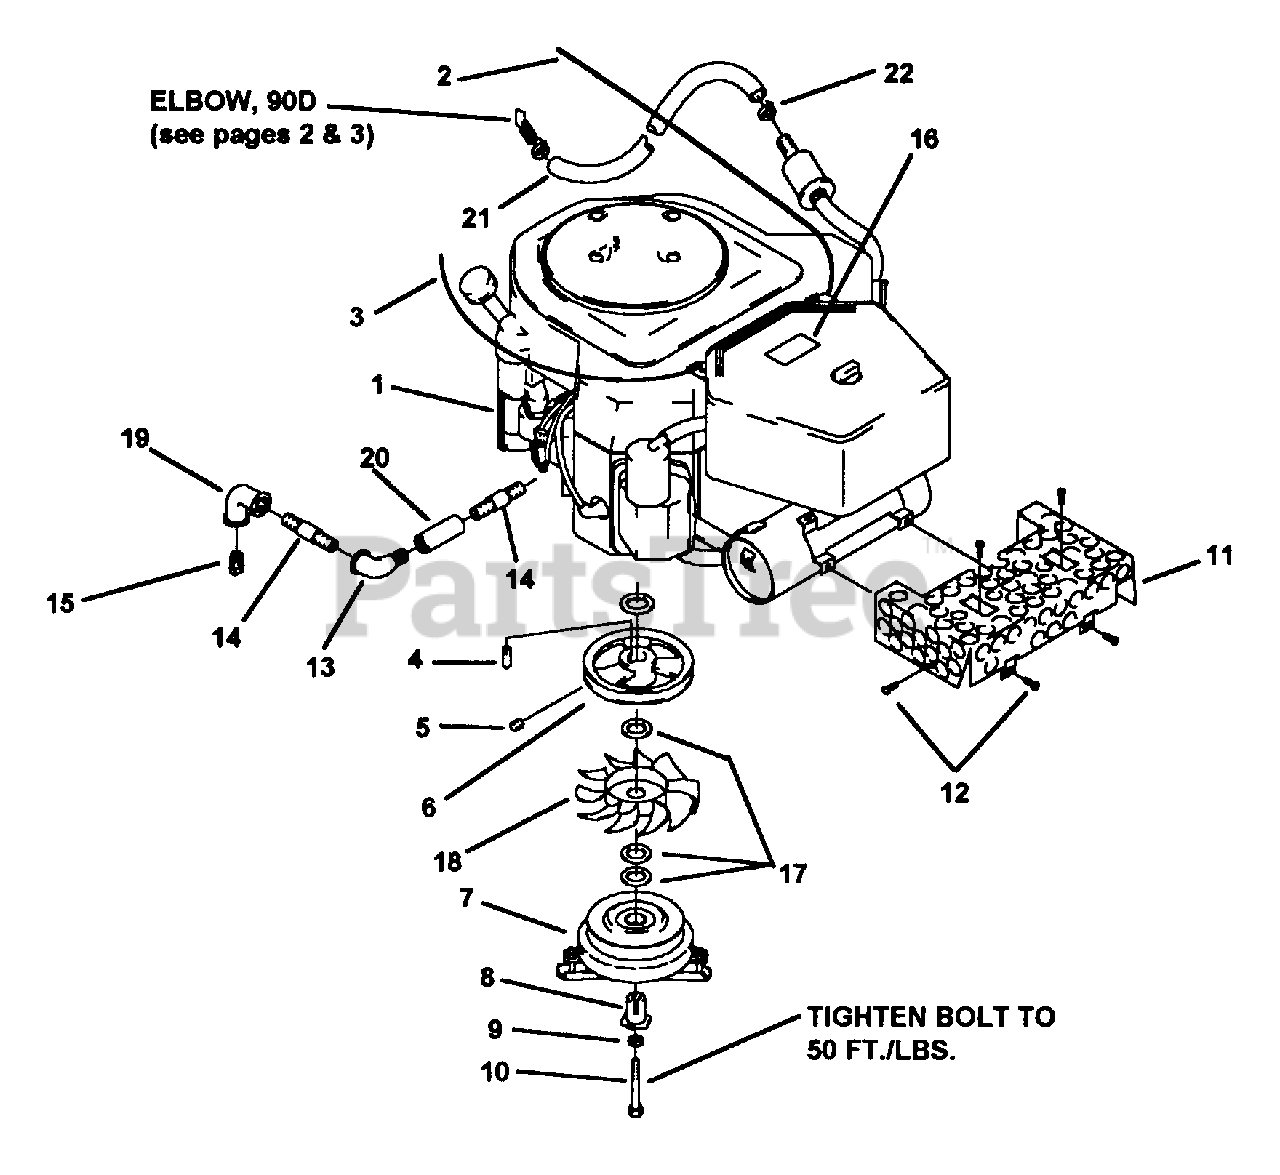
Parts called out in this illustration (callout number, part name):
1	* ENGINE, 18.5HP KOHLER COMMAND OHV, VERTICAL SHAFT
1	* ENGINE, 22HP KOHLER COMMAND OHV, VERTICAL SHAFT
2	CABLE, THROTTLE 18 & 22 HP
3	CABLE, CHOKE 18 & 22 HP
4	KEY, SQUARE, 1/4" X 1"
5	SETSCREW, SOCKET HD., 5/16-18 X 3/8"
7	CLUTCH, ELECTRIC, 1" BORE
8	BUSHING, CLUTCH
9	LOCKWASHER, 7/16" SPLIT SPRING
10	CAPSCREW, 7/16-20 X 3-1/4" GR.5
11	MUFFLER GUARD, COMMAND ENGINE
12	SCREW, SHEET METAL, #8 X 1/2"
13	ELBOW, STREET, 3/8", 90DEG. SCH 40
15	PLUG, PIPE 3/8"
16	DECAL, "PERIODICALLY CLEAN"
17	WASHER, SHIM
18	FAN, 7" DIA. 10 BLADE CW
22	CLAMP, HOSE SPRING TYPE 1/2" O.D.
